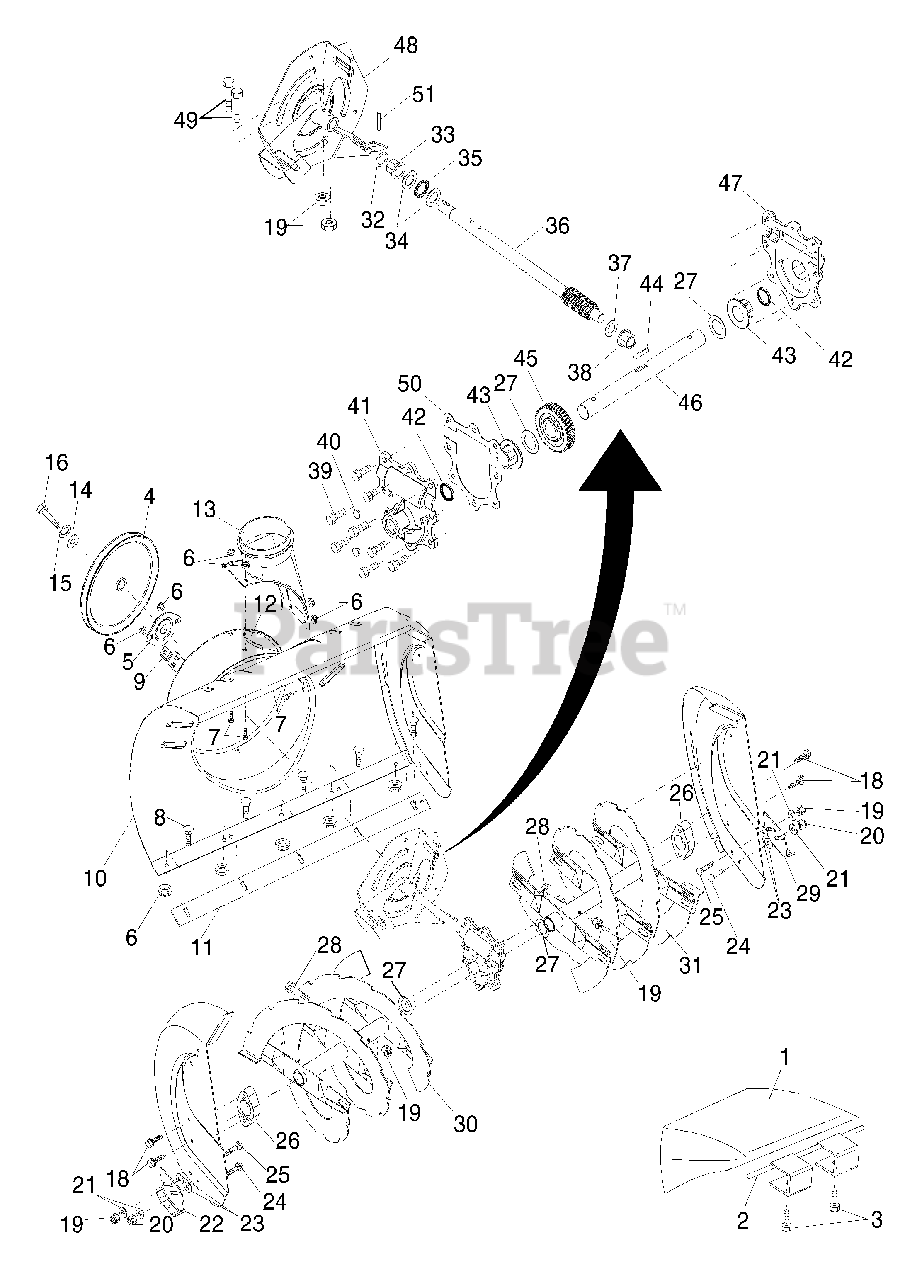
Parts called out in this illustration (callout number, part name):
1	Bag, Weight
2	Bracket, Weight Bag
3	Screw, Hex Head 5/16-18 x 1-1/2
4	Pulley, Impeller
5	Bearing Assembly, Flange
6	Nut, Hex Flange 5/16-18
7	Bolt, Flat Head, Carriage 5/16-18 x 5/8
8	Bolt, Carriage 5/16-1 8 x 5/8
9	Nut, Cage 3/8-16
10	Housing, Auger
11	Bar, Scraper
12	Bracket, Corner Discharge
13	Base, Discharge Chute
14	Washer, Flat
15	Washer, Lock 5/16
16	Screw, Hex Head 5/16-18 x 3/4
18	Screw, Hex Head 5/16 x 1
19	Nut, Hex Lock 1/4-20
20	Nut, Hex Lock 5/16-18
21	Washer, Flat
22	Skid Plate, RH
23	Washer, Nylon, Friction
24	Bolt, Carriage 5/16-18 x 3/4
25	Bolt, Shoulder
26	Bearing, Auger
27	Washer, Thrust, 1"
28	Bolt, Shoulder 1/4-20 x 2
29	Skid Plate, LH
30	Auger Assembly, RH
31	Auger Assembly, LH
33	Bushing, Flange 3/4
34	Washer, Thrust 3/4
35	Bearing, Thrust 3/4
36	Shaft, Impeller
37	Washer, Thrust 5/8
38	Bushing, Flange 5/8
39	Screw, Hex Head 5/16-18 x 3/4
40	Plug, Case
41	Housing, Gearbox, RH
43	Bushing, Flange, 1"
44	Key, Square 1/4 x 1/4 x 7/8
45	Gear, Worm
46	Shaft, Auger
47	Housing, Gearbox, LH
48	Impeller Assembly
49	Screw, Hex Head 1/4-20 x 1-5/8
50	Gasket, Gearbox
51	Pin, Roll 3/16 x 1-1/8
